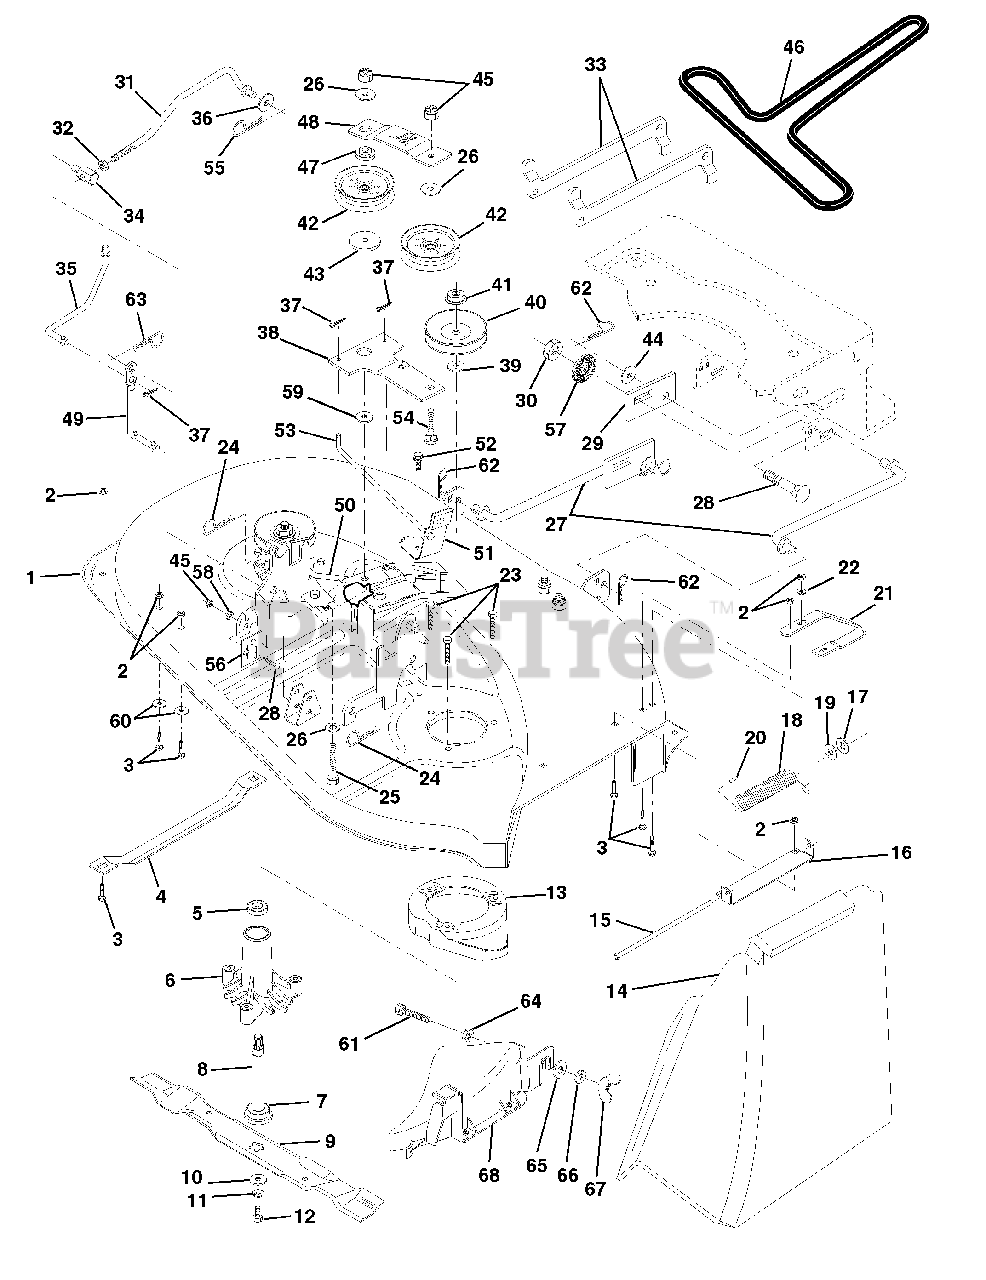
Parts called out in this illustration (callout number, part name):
1	Mower Deck Assembly
2	Nut, Crownlock 5/16-18
3	Bolt, Carriage 5/16-18 x 3/4
4	Runner, L.H.
6	Housing, Mandrel
8	Shaft and Bearing Assembly, Mandrel
10	Washer, Hardened
11	Washer, Lock 3/8
12	Bolt, Hex 3/8-24 x 1-1/4 Grade 8
13	Stripper, Mower, Vented
14	Shield, Deflector
15	Rod, Hinge
16	Bracket Assembly, Deflector
18	Spring, Deflector
19	Washer 11/32 x 5/8 x 16 Gauge
20	Cap, Sleeve
21	Runner, R.H.
22	Washer 11/32 x 3/4 x 16 Gauge
23	Screw, Thdrol. Hex Hd. Zinc Mwr
24	Retainer, Spring
25	Bolt, Carriage 3/8-16 x 2-1/4
26	Washer 13/32 x 1 x 12 Gauge
27	Link Assembly, Front
28	Bolt, Rd Hd Sq Nk 3/8-16 x 1
29	Plate, Slide Link
30	Nut, Lock Hex w/Wsh 3/8-16
31	Clutch Rod, Primary
32	Nut, Hex, Jam 3/8-16
33	Arm, Suspension, Rear
34	Trunnion 3/8-16
35	Clutch Rod, Secondary
36	Washer 13/32 x 13/16 x 16 Gauge
37	Pin, Cotter 3/32 x 3/4
39	Washer .150 Thick
40	Pulley, Mandrel
41	Nut, Flangelock 9/16
42	Pulley, Flat Idler
43	Spacer, Retainer
45	Nut, Crownlock 3/8-16
46	Belt
47	Spacer, Idler Arm
48	Stiffener, Idler Arm
49	Rod, Pivot
50	Rod, Brake, L.H.
51	Brake Assembly
52	Screw, Hex Washer Head, Thd., Roll. 5/16-18 x 3/4
53	Rod, Brake, R.H.
54	Bolt, Carriage 3/8-16 x 1-3/4 Grade 5
55	Spring, Retainer
56	Adjustment Plate, Rear Link, L.H.
57	Washer, Serrated 13/32 x 1
58	Washer 13/32 x 3/4 x 12 Gauge
59	Washer, Hardened
60	Washer 11/32 x 11/16 x 12 Gauge
61	Bolt 3/8-16 x 1-1/4
62	Retainer, Spring
63	Retainer, Spring
64	Nut Centerlock 3/8-16
65	Washer 13/32 x 1-1/4 x 16
66	Washer Lock Hvy Hlcl
68	Cover Asm. Mulching 38"
